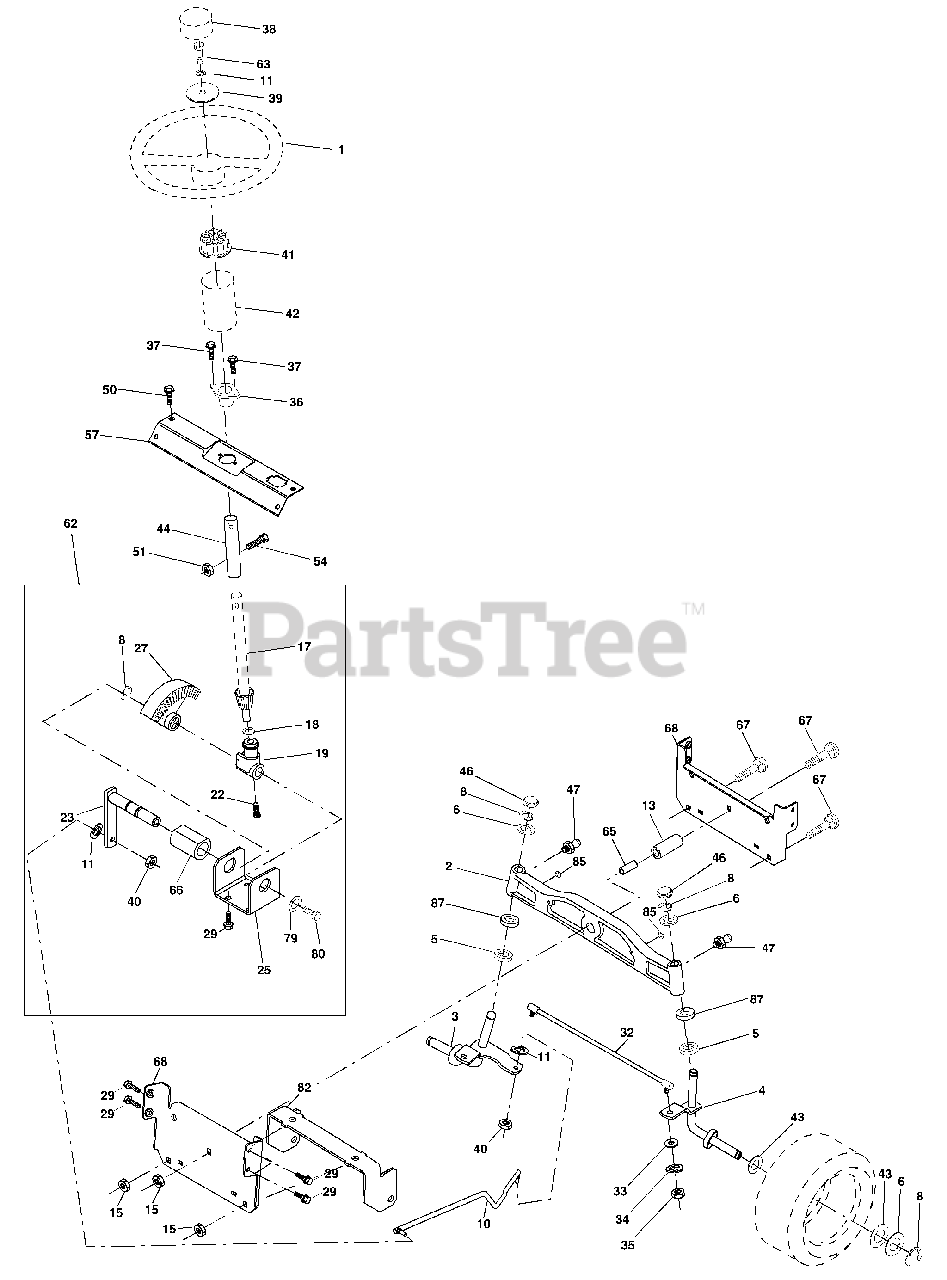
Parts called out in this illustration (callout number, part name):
1	Wheel Steering
2	Axle Cast Lt Machined
3	Spindle Asm LH
4	Spindle Asm RH
5	Bearing Race Thrust Harden
6	Washer 25/32 X 1-5/8 X 16 Ga
8	Ring Klip #t5304-75
10	Link Drag
11	Washer Lock Hvy Hlcl Spr 3/8
13	Spacer Brg Axle Front
15	Nut Hex Flange Lock
17	Shaft Asm Strg Private Label
18	Washer Thrust 515 x 750 x 033
19	Support Shaft
22	Screw Hex Wsh Hd Torx
23	Shaft Asm Pittman
25	Bracket Steering
27	Gear Sector 22 Teeth
29	Screw 3/8-16 x 3/4
32	Rod Tie
33	Washer 11/32 x 3/4 x 16 Ga.
34	Washer Lock Hry Hlcl Spr 5/16
35	Nut Crownlock 5/16 - 24 UNF
36	Bushing Strg
37	Screw TT #32.5 x 5 x 3/8 Flange
38	Cap Wheel Steer
39	Washer 13/32 x 1-1/20 x 11 Ga
40	Nut Lock Center 3/8-24 Unf
41	Adaptor Wheel Strg
43	Washer 25/32 X 1 1/4 X 16 Ga
44	Extension Steering Non-adjust
46	Cap Spindle Fr Top Blk
47	Fitting Grease
50	Screw Hexwsh Thdrol 1/4-20 x 3/4
51	Nut Lock Hex W/Ins 5/16-18 UNC
54	Bolt Fin Hex 5/16-18 UNC x 1-1/4
57	Support Shaft Steering
62	Steering Assembly
63	Bolt Fin Hex 3/8-16 UNC x 1 Gr. 5
65	Spacer Brace Axle
66	Bearing Arm Pittm-an
67	Bolt Rdhd Sqn 3/8-16 x 2-1/4
68	Brace, Axle
79	Washer 13/32 x 1-1/4 x 12 Ga.
80	Bolt Hex Nylon 3/8-16 x 3/4
82	Bracket Susp Chassis Front
85	Fastner Christmas Tree
87	Washer Flat .781 x 1-1/2 x .14
